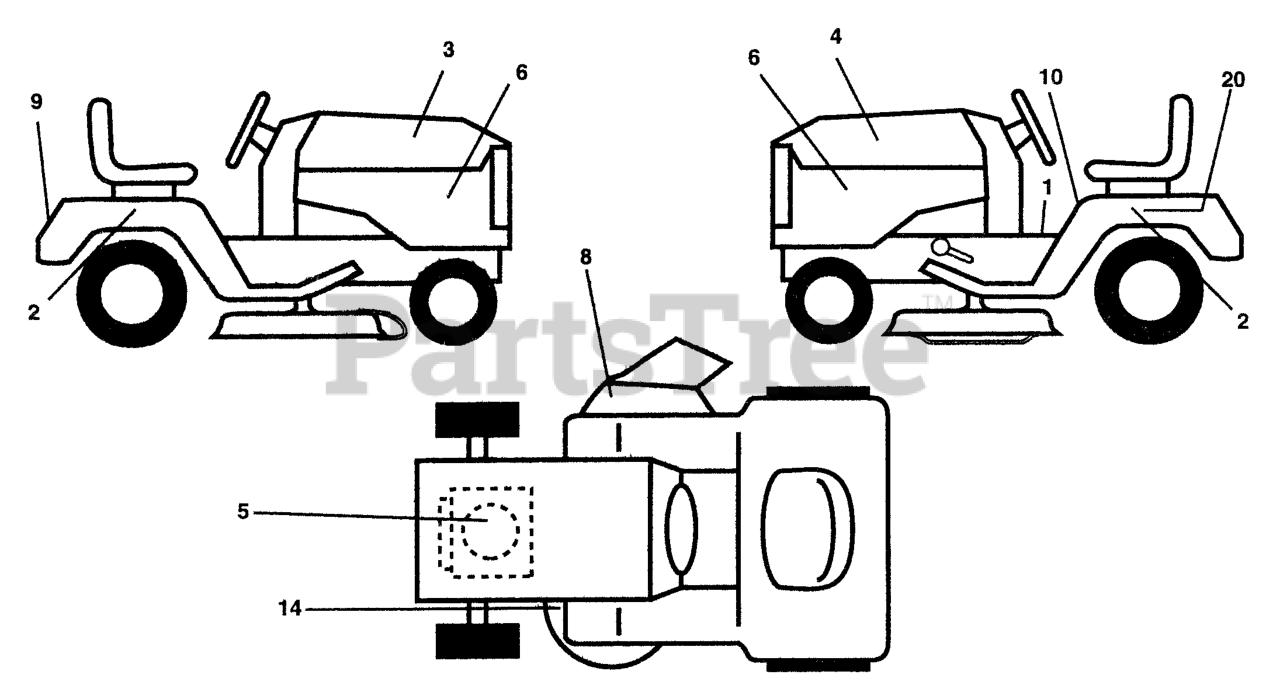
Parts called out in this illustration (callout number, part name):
3	DECAL, HOOD LH LTH120
4	DECAL, HOOD RH LTH120
5	DECAL HP ENGINE
6	DECAL PNL SIDE
8	DECAL WARNING (ENGLISH/FRENCH)
9	DECAL FENDER HUSQ
10	DECAL FENDER DANGER
14	DECAL V-BELT SCHEMATIC
20	DECAL BTRY SYMBOLS
